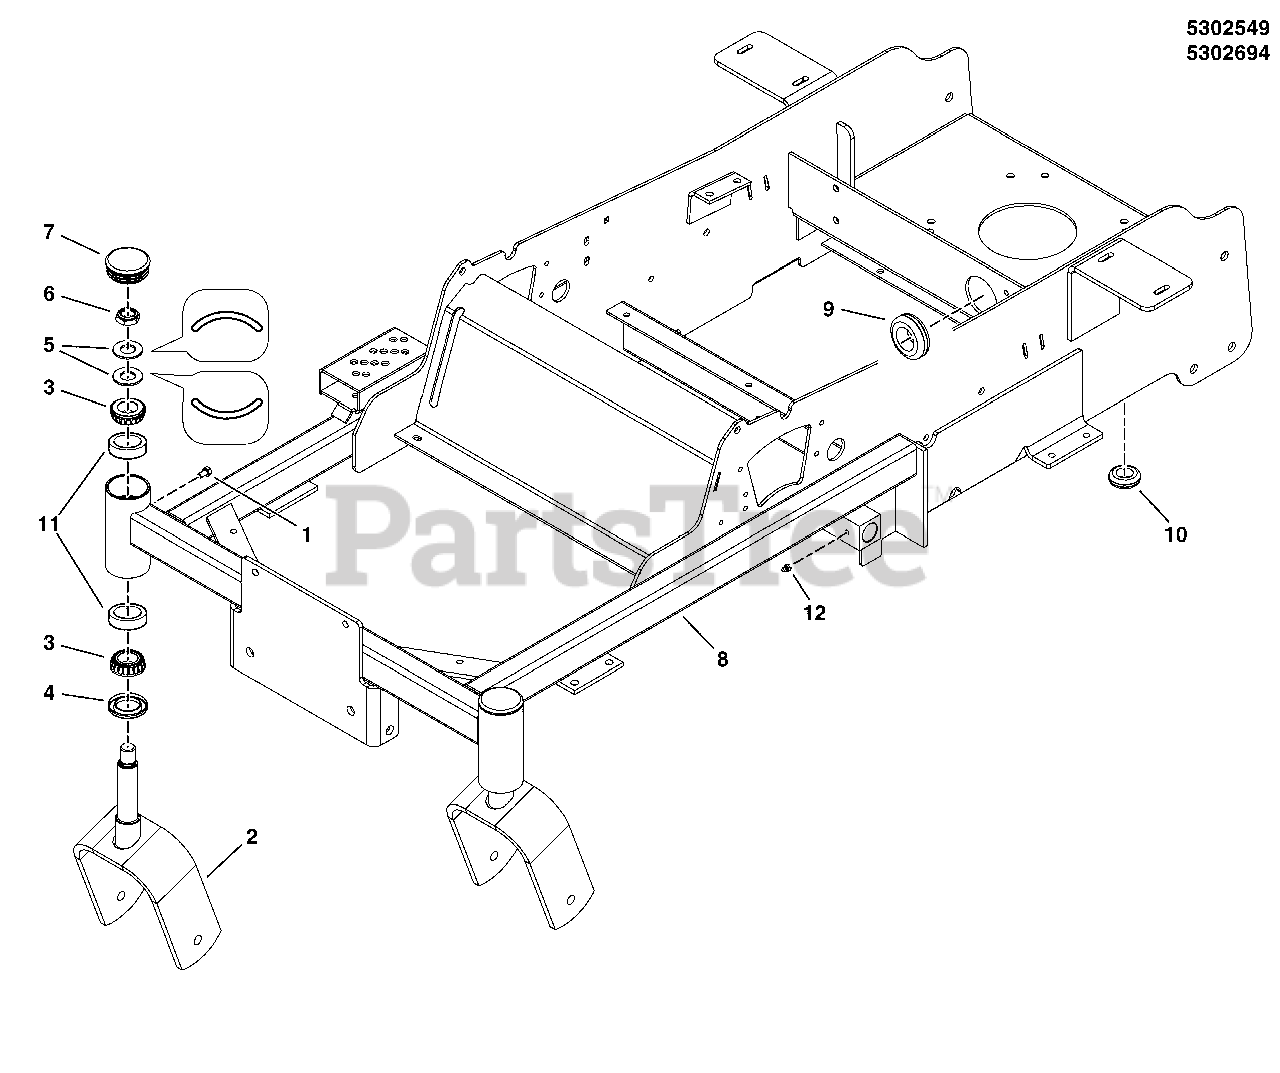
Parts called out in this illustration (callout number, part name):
1	BOLT, 1/4-28 X 1/2, GD5 YZ
2	WELD, CASTER YOKE - RED
3	BEARING, TAPERED ROLLER, 1"
4	SEAL, GREASE
5	WASHER, BELLEVILLE - 1.500 X .755
6	NUT, 3/4-16, HEX JAM NYLON LOCK
7	CAP, CASTER SPINDLE, LOW PROFILE
8	WELD, FRAME, 50XT-48 - RED
8	WELD, MAIN FRAME, 48 - RED
9	GROMMET, 2" ID
10	GROMMET, 7/8
11	CUP, BEARING (SV)
12	GREASE FITTING, 1/4-28 STRAIGHT
